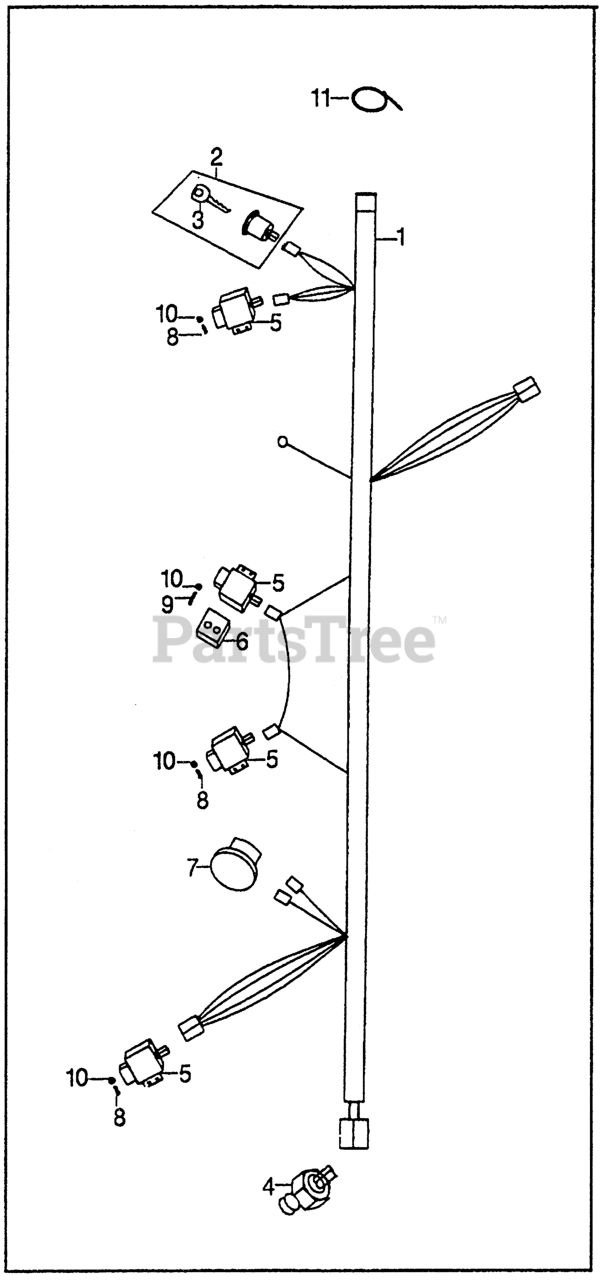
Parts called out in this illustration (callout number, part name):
1	WIRE HARNESS ASSY.
2	SWITCH ASSY., COMBINATION
3	KEY, IGNITION
4	SWITCH, BALL
5	LIMIT, SWITCH
6	SPACER, SWITCH
7	METER ASSY., HOUR
